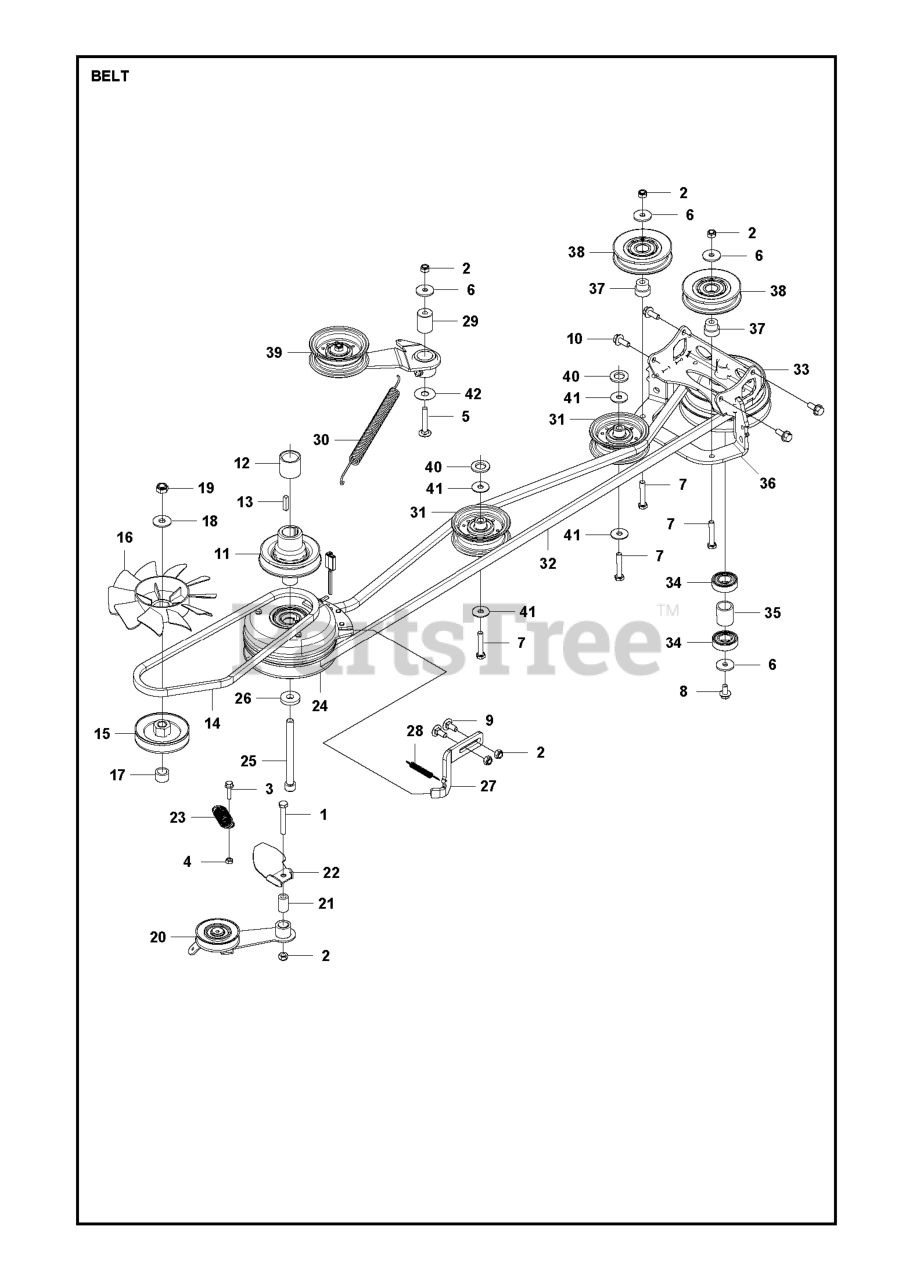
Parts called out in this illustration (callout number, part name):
2	LOCKNUT M8
7	SCREW
34	BALL BEARING 6004-2RS1
